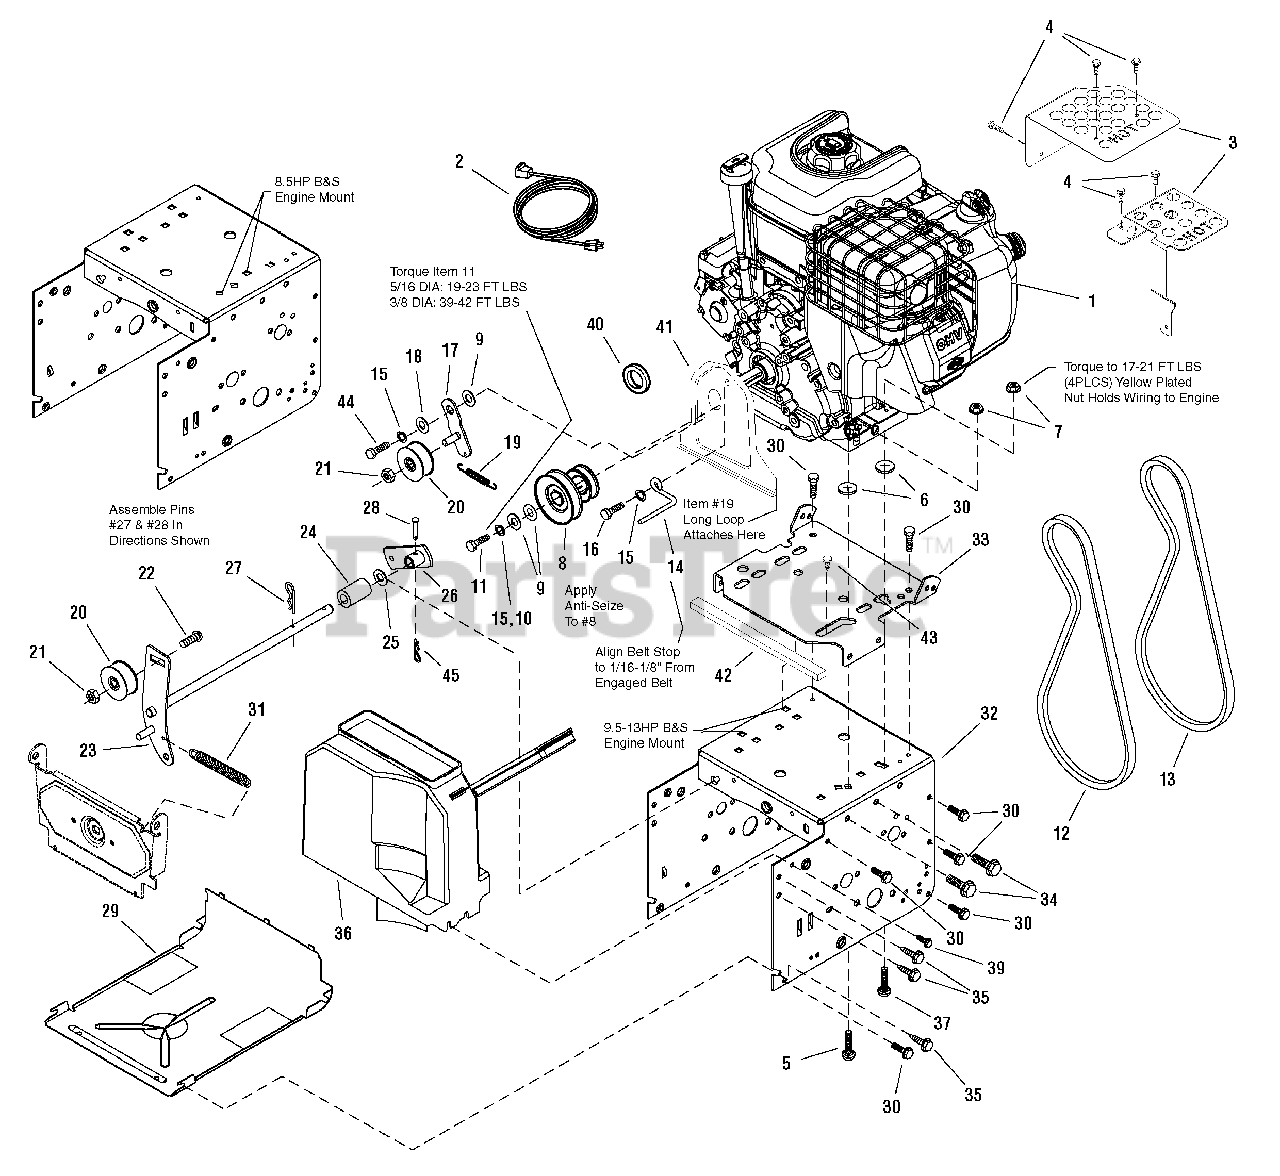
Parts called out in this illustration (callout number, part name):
1	* ENGINE, 11.5GT B&S Mod. #15C114-0117-E8
1	* ENGINE, 13.5GT B&S Mod. #20M214-0117-E1
2	CORD, Electric Start
3	GUARD, Muffler
4	SCREW, Hex Washer Head Taptite, 10-24 x 3/8
5	CARRIAGE BOLT, 5/16-18 x 1-1/2
6	NUT, Speed
7	NUT, Hex Flange 5/16-18 Whiz Lock
7	NUT, Hex Flange 5/16-18 ESNA
8	PULLEY, Engine
9	WASHER, 3/8
9	WASHER, 5/16-1
10	LOCKWASHER, Spring 3/8
11	CAPSCREW, Hex Head 3/8-24 x 1-1/4 G8
11	CAPSCREW, Hex Head 3/16-24 x 1-1/4 G8
12	V-BELT, Drive, 3L 33.13
13	V-BELT, Auger, 4L 36.50
14	STOP, Belt
15	LOCKWASHER, Spring 5/16
16	CAPSCREW, Hex Head 5/16-24 x 3/4 G5
17	IDLER BRACKET ASSEMBLY, Drive Belt
18	BUSHING, Idler Bracket
19	SPRING, Extension Idler
20	IDLER, Plastic Ball Bearing
21	NUT, Hex Centerlock Jam 3/8-16
22	CARRIAGE BOLT, 3/8-16 x 1-1/4
23	IDLER, Auger
24	SPACER/AUGER BRACKET
25	WASHER, 1/2
26	BRACKET & HUB ASSEMBLY, Spring
27	PIN, Hair
28	PIN, Clevis
29	PANEL, Bottom
30	SCREW, Hex Washer Head Taptite 1/4-20 x 5/8
31	SPRING, Extension Auger Idler
32	FRAME, EZ Turn Axle
33	PLATE, Engine Mount
34	SCREW, Hex Washer Head Taptite 5/16-18 x 1/2
35	SCREW, Hex Washer Head Taptite 5/16-18 x 3/4
36	COVER, Belt w/Toolbox B&S
39	SCREW, 1/4-AB x 3/4 Hex
40	SHAFT, Seal
41	SEAL, Plate
42	SEAL, Strip
43	CLIP, Pine Tree
44	CAPSCREW, Hex Head 5/16-24 x 1 G8
45	PIN, Cotter, 1/4
